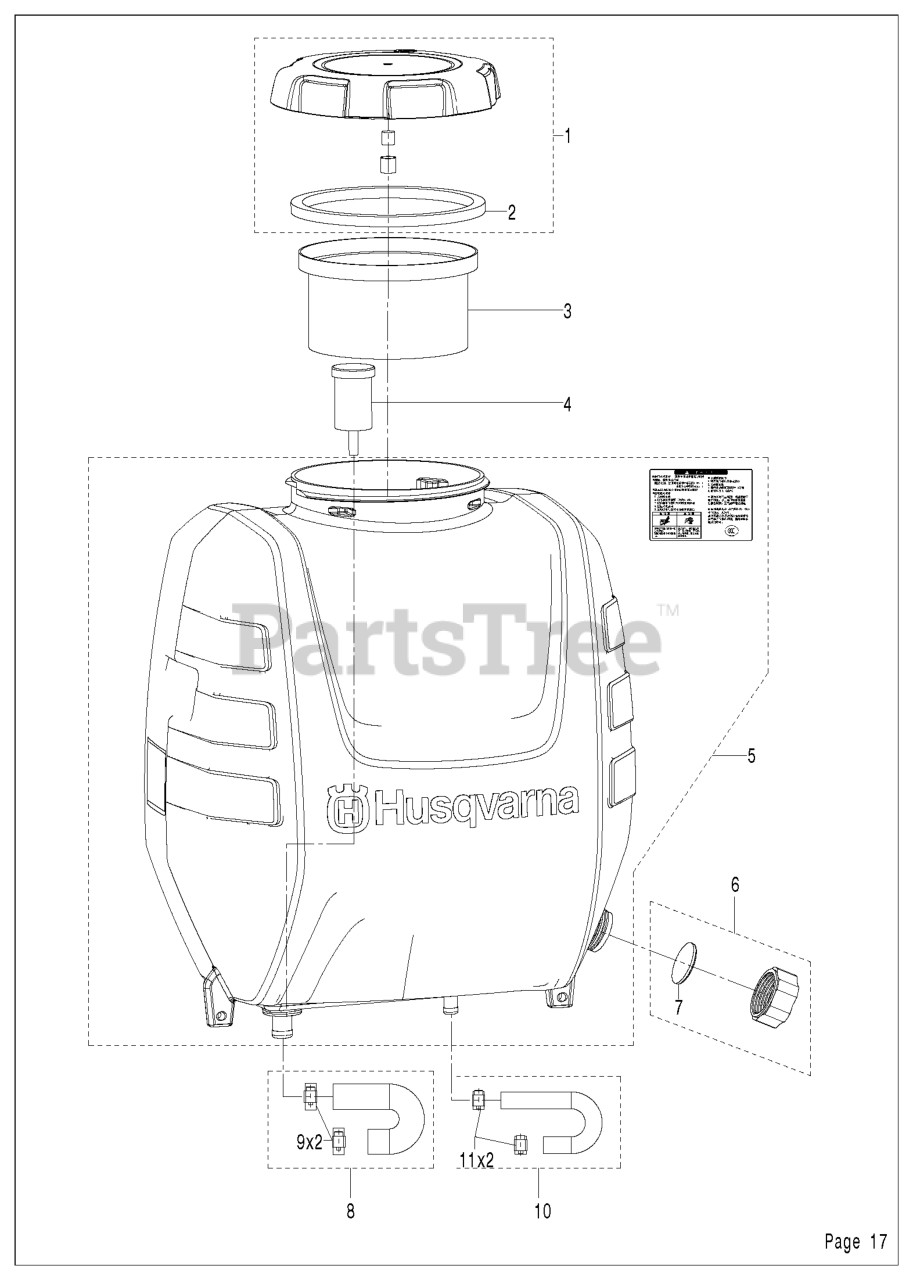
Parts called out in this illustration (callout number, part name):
1	DECAL.FENDER.WARNING.ENG
2	RP.DECAL.BADGE.170MM.TEXTLOGO
3	DECAL, EMBLEM PANEL SD
4	DECAL, NO STEP
5	DECAL.WARNING.CUST.RESP.E85.
6	DECAL, REPLACEMENT
7	DECAL, CAUTION
8	DECAL.MOWER.SCH.48/54
9	DECAL BTRY SYMBOLS
10	DECAL.PEDAL.HUSQ.CROWN
11	DECAL.WARN.RESERVE.FUEL
